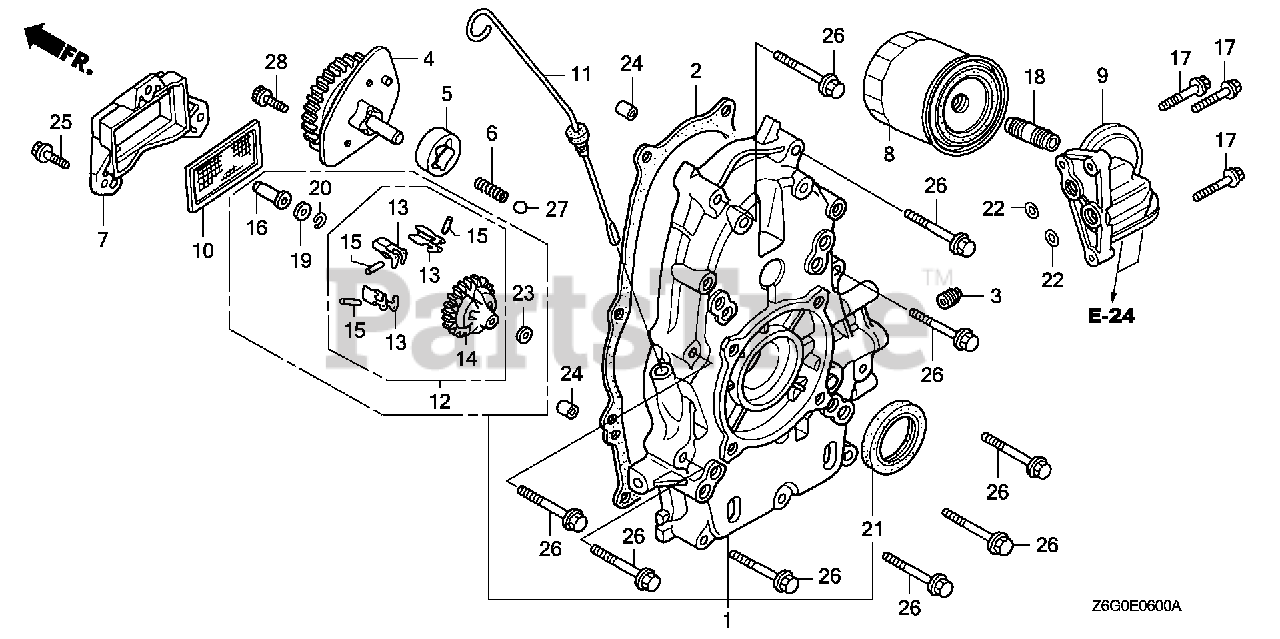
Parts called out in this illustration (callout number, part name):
1	COVER ASSY., CRANKCASE
2	GASKET, CASE COVER
4	COVER ASSY., OIL PUMP (THREE BOLTS)
5	ROTOR, OIL PUMP (OUTER)
6	SPRING, RELIEF VALVE
7	COVER, OIL FILTER
8	FILTER, OIL (FILTECH TOYO ROKI) (SOLD INDIVIDUALLY)
8	FILTER, OIL (SOLD INDIVIDUALLY)
8	FILTER, OIL (TOYO ROKI) (SOLD INDIVIDUALLY)
9	BASE, OIL FILTER
10	SCREEN, OIL FILTER
11	DIPSTICK, OIL
12	GOVERNOR ASSY.
13	WEIGHT, GOVERNOR
14	HOLDER, GOVERNOR WEIGHT
15	PIN, GOVERNOR WEIGHT
16	SLIDER, GOVERNOR
17	BOLT, FLANGE (6X28) (CT200)
18	HOLDER, OIL FILTER
19	WASHER (6X16)
20	CLIP, GOVERNOR HOLDER
21	OIL SEAL (38X58X9)
22	O-RING (11.8X2.4)
23	WASHER, PLAIN (6MM)
24	PIN, DOWEL (8X14)
25	BOLT, FLANGE (6X20)
26	BOLT, FLANGE (8X50)
27	BALL, STEEL (#12) (3/8)
28	BOLT, SOCKET (6X16)
